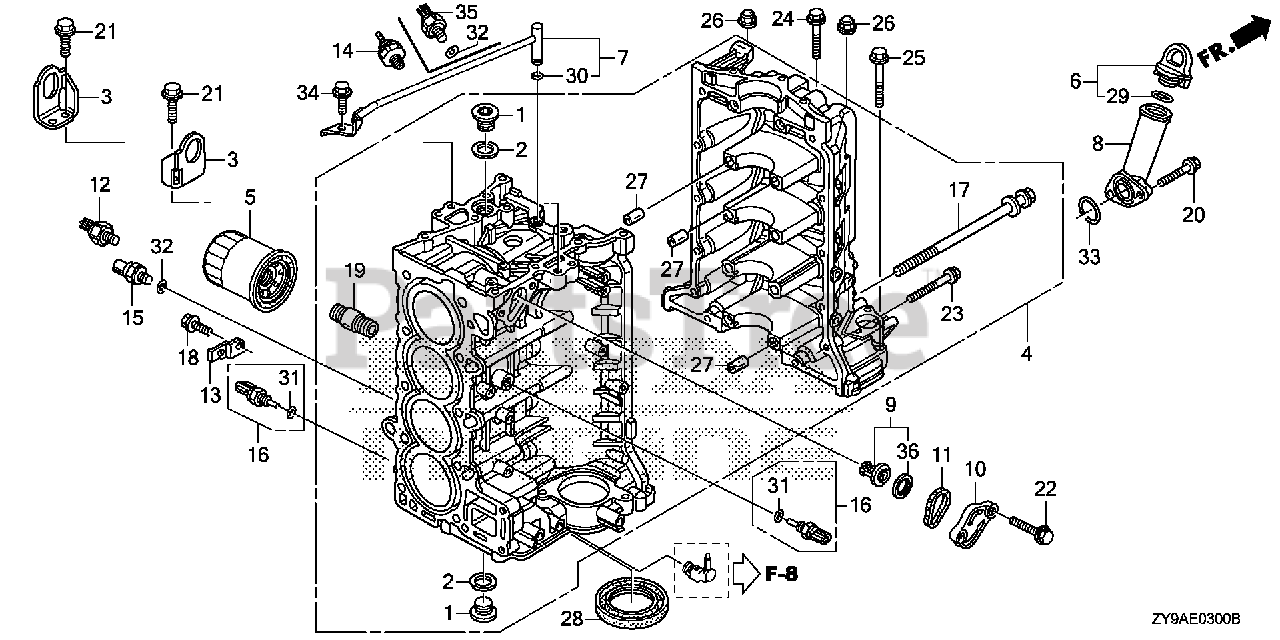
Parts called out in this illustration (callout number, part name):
1	BOLT, SEALING (24MM)
2	WASHER, SEALING (24MM)
3	HANGER, ENGINE
4	BLOCK ASSY., CYLINDER *NH8* (DARK GRAY)
5	FILTER, OIL (FILTECH TOYO ROKI) (SOLD IN MULTIPLES OF 30)
5	FILTER, OIL (HONEYWELL) (SOLD IN MULTIPLES OF 30)
5	FILTER, OIL
6	CAP ASSY., OIL FILLER
8	EXTENSION, OIL FILLER
9	THERMOSTAT ASSY.
10	COVER, THERMOSTAT
11	O-RING, THERMOSTAT COVER
12	SENSOR, KNOCK
13	BRACKET, CLIP B
14	SWITCH ASSY., OIL PRESSURE
15	SWITCH ASSY., OIL PRESSURE
16	SENSOR ASSY., WATER TEMPERATURE
17	BOLT-WASHER (10X105)
18	BOLT, FLANGE (6X14) (CT200)
19	HOLDER, OIL FILTER
20	BOLT, FLANGE (6X25)
21	BOLT, FLANGE (8X20)
22	BOLT, FLANGE (6X22)
23	BOLT, FLANGE (6X32)
24	BOLT, FLANGE (8X35)
25	BOLT, FLANGE (8X45)
26	NUT, FLANGE CAP (8MM)
27	PIN, DOWEL (12X14)
28	OIL SEAL (80X98X10) (ARAI)
29	O-RING (18.1X3.6)
30	O-RING (6.5X1.5)
31	O-RING (9.5X1.9)
32	O-RING (13X1.5) (ARAI)
33	O-RING (28.3X2.4) (NOK)
34	BOLT, FLANGE (6X14)
36	RUBBER, RING
